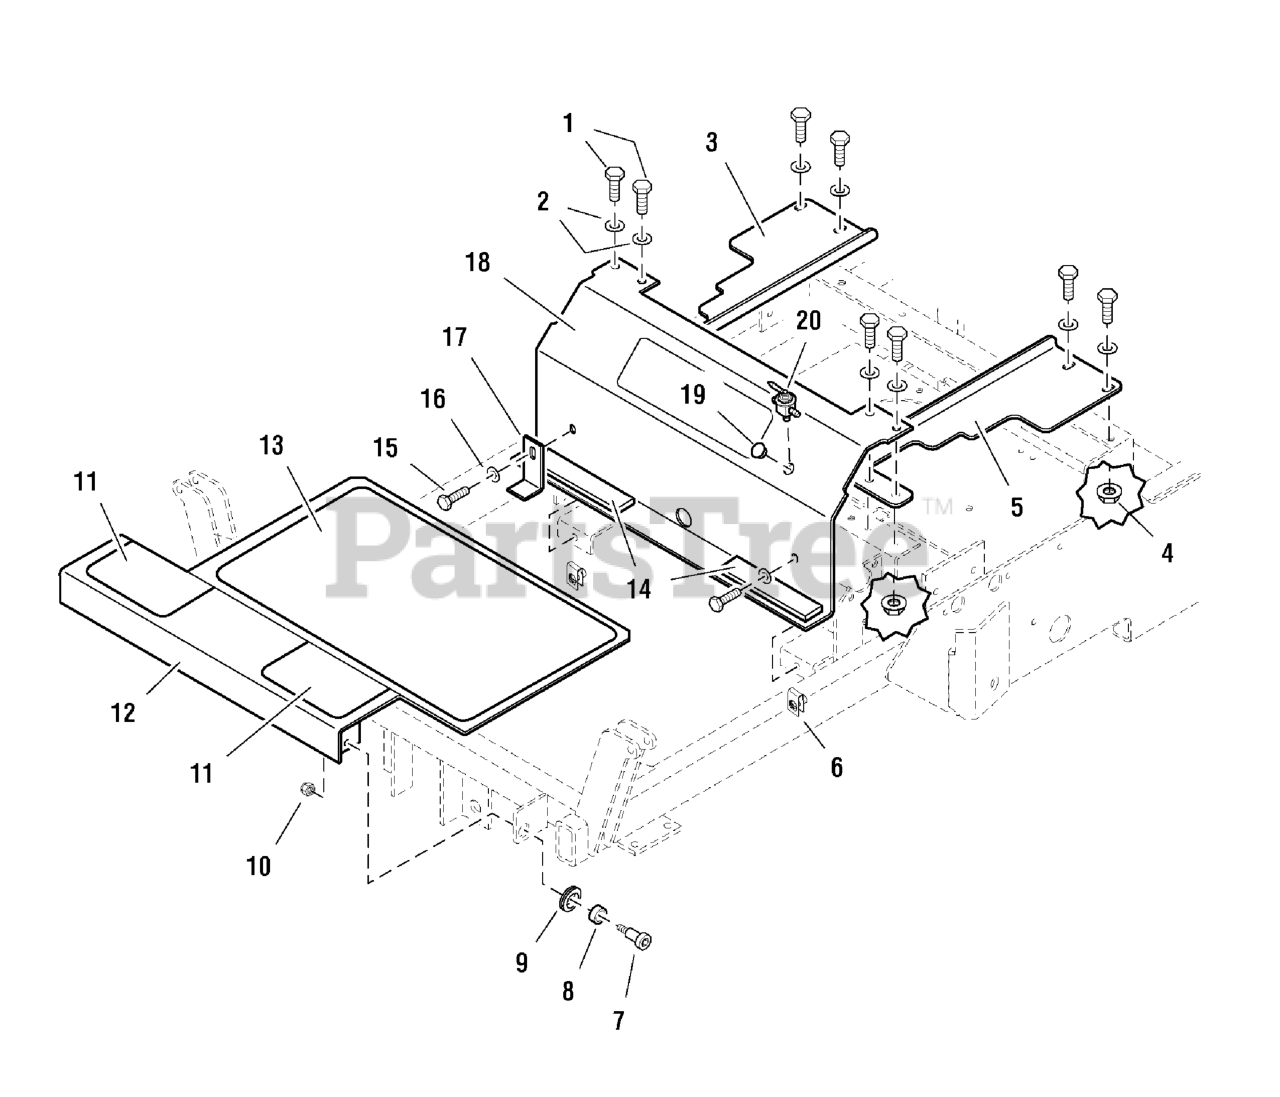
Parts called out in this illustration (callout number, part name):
1	BOLT, 3/8-16 X 1" GD5 CZ
2	WASHER, 3/8 SAE
3	SHIELD - RH
4	NUT, 3/8-16 Hex Serrated Flange
5	SHIELD - LH
6	BODY CLIP, 5/16-18-7GA MATERIAL
7	SHOULDER BOLT, 3/8 x 5/8
8	SLEEVE
9	GROMMET
10	NUT, 5/16-18 Hex Nylon Lock
11	SAFETY WALK
12	FLOOR PAN
13	SAFETY WALK, 11.50 X 19.00
14	RUBBER PAD
15	BOLT, 5/16-18 X 3/4 GD5
16	WASHER, 5/16" SAE
17	HOLD DOWN
18	BRAKE COVER PANEL ASSEMBLY
19	HOLE PLUG
20	FUEL SHUT OFF VALVE
